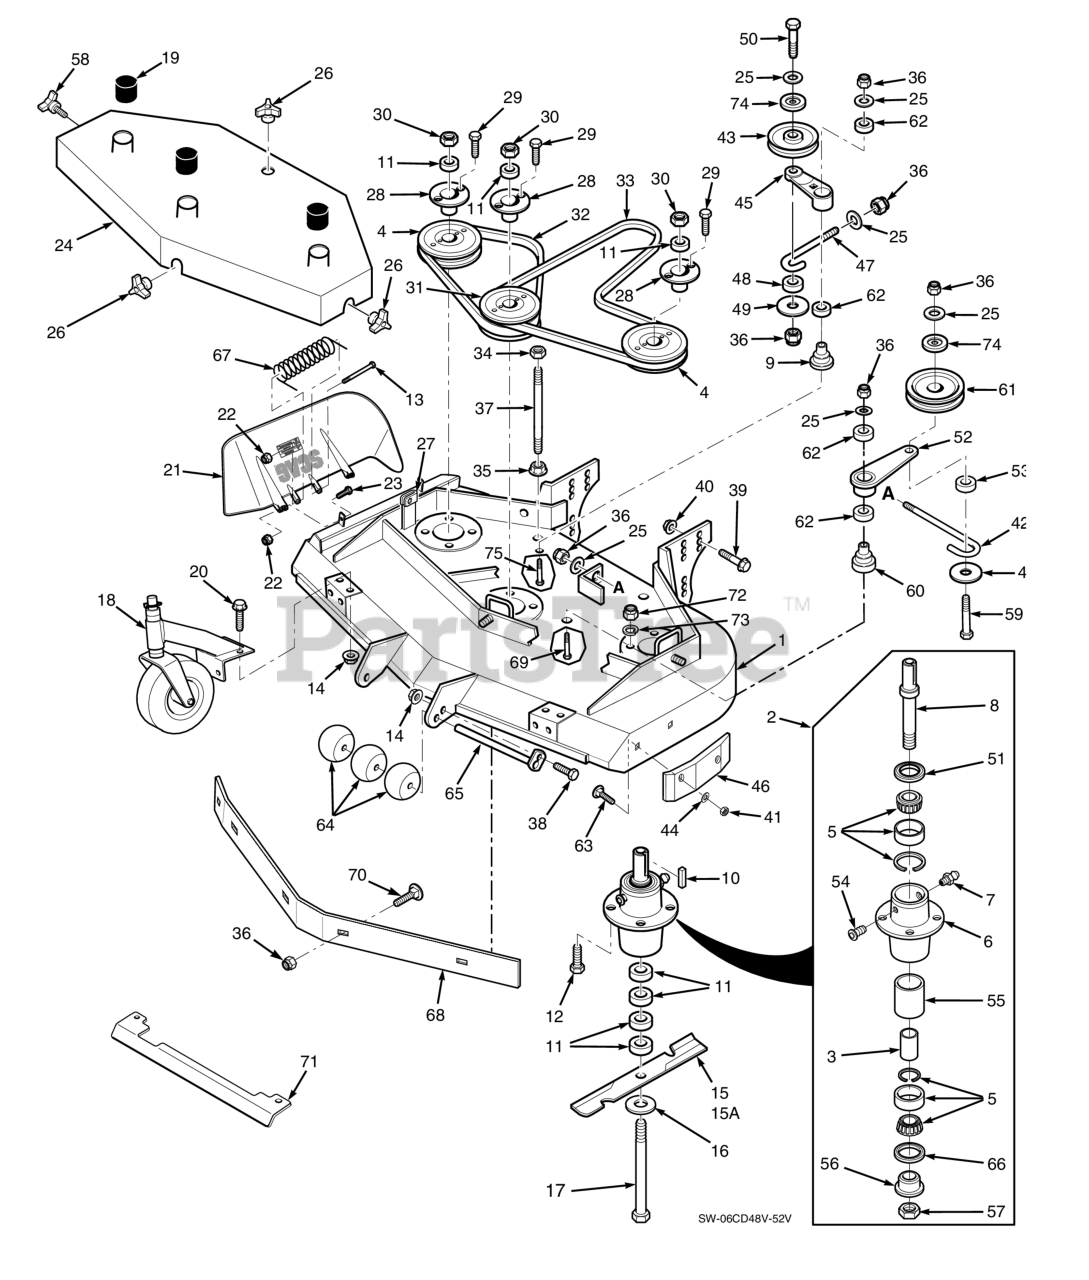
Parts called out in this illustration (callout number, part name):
1	Cutter Deck w/Decals
2	Cutter Spindle Assembly
3	SLEEVE, CUTTER SPINDLE
4	Pulley, 6.35 O.D. (Diesel Engine)
5	Tapered Bearing Set (Two Bearings W/Race)
6	Housing, Spindle
7	GREASE FITTING, STR. 1/4-28 SELF TAP.
8	Spindle Shaft, Tapered Brng
9	Idler Pivot
10	Key, 1/4 x 1/4 x 2.0"
11	Spacer, Cutter Blade - Small
12	Bolt, Hex Head 5/16-18 x 1-1/2" Grade 8
13	Bolt, 5/16-18 x 4-3/4" Hex Head
14	Nut, Serrated Flange 5/16-18 (Right Front Engine Mounting, Briggs and Kohler Only)
15	Cutter Blade, 21" Standard
15A	Cutter Blade, High Lift (61" Deck)
16	Flatwasher, 5/8-.688 x 1-3/4 x .134 HD
17	BOLT, HEX HEAD, 5/8-11 X 9-1/2 GR.5
18	Caster Assembly
20	Capscrew, 5/16-18 x .75 Serrated Flange Hex Head
21	Discharge Chute Advantage - Large
22	HEX NUT, ELASTIC STOP LOCK, 5/16-18
23	Bolt, Hex Head 5/16-18 x 1-1/2" (Right Front Engine Mounting, Briggs and Kohler Only)
24	Belt Cover (Incl. decals)
25	Flatwasher, 3/8 (.391 x .938 x .105 HD) Grade 8
26	WINGNUT, PLASTIC 3/8-16 X .875
27	U-Nut, 3/8-16 (short)
28	Hub, Tapered 1-1/8" Bore
29	Bolt, Hex Head 1/4-20 x 1" Grade 8 Black
30	Hex Locknut, Elastic Stop, 3/8-16
31	Pulley, Double Groove, 6.35/5.75 O.D.
32	BELT, RH BLADE DRIVE 61" DECK
33	BELT, BLADE DRIVE SLM 48
34	Bolt, Hex Head 3/8-16 x 1" Ser. Flg.
35	NUT, 3/8-16 SERRATED FLANGE HEX HEAD
36	HEX NUT, ELASTIC STOP LOCK, 3/8-16
37	Bolt, 5/16-18 x 1" Hex Head
38	Bolt, Heax Head 5/16-18 x 1" (48V / 52V)
39	Serr. Fl. Hex Head Capscrew, 1/2-13 x 1-3/4
40	Nut, Elastic Stop 1/2-13, (STT-52 & STTII-52)
41	Nut, Center Lock, 5/16-18(32)
42	J-Hook, Idler Pulley
43	IDLER PULLEY, "V" GROOVE
44	Flatwasher, 5/16-.344 x .688 x .065 (48V / 52V)
45	Idler Arm Assembly
46	Pad, Deck Wear
47	J-HOOK, IDLER PULLEY
48	SPACER, J PULL ROD
49	Flatwasher, 3/8 (.375 x 1-1/2" x 16 ga.)
50	Capscrew, Hex Head 3/8-16 x 2-1/2"
51	SEAL, 2.00 O.D. X 1.50 BORE
52	Idler Arm Assy.
53	SPACER, J-PULL ROD
54	RELIEF FITTING, TAPERED BEARING SPINDLE
55	Spacer, Outside, Cutter Spindle
56	SPINDLE BUSHING, BOTTOM
57	Nut , Spec ial 1 -1/ 1 6 - 1 8
58	Knob, w/stud 3/8-16 x 1-1/4"
59	Capscrew, Hex Head 3/8-16 x 3-3/4"
60	Pivot, Idler - Short
61	Idler Pulley, Belt Clutch
62	BEARINGS, BALL, NEUTRAL RETURN
63	Bolt, 5/16-18 x .75 RHSN Carriage
64	Wheel, Anti-Scalp
65	Shaft Weldment, Guide Roller
66	Seal, 2.00" O.D. x 1.625" Bore
67	Spring, Discharge Chute
68	Baffle Custom-Cut, 61V (7-Position)
69	Capscrew, Hex Head 3/8-16 x 3.25"
70	Carriage Bolt, 3/8-16 x 1.0"
71	Heatshield, 20" Large Frame
72	Lock Nut, 5/16-18 Elastic Stop Grade 8
73	Lockwasher, 5/16 (.317 x .586 x .078) Helical Spring
74	Quick Pin, 5/16" Dia.
75	Capscrew, Hex Head 3/8-16 x 2.75"
